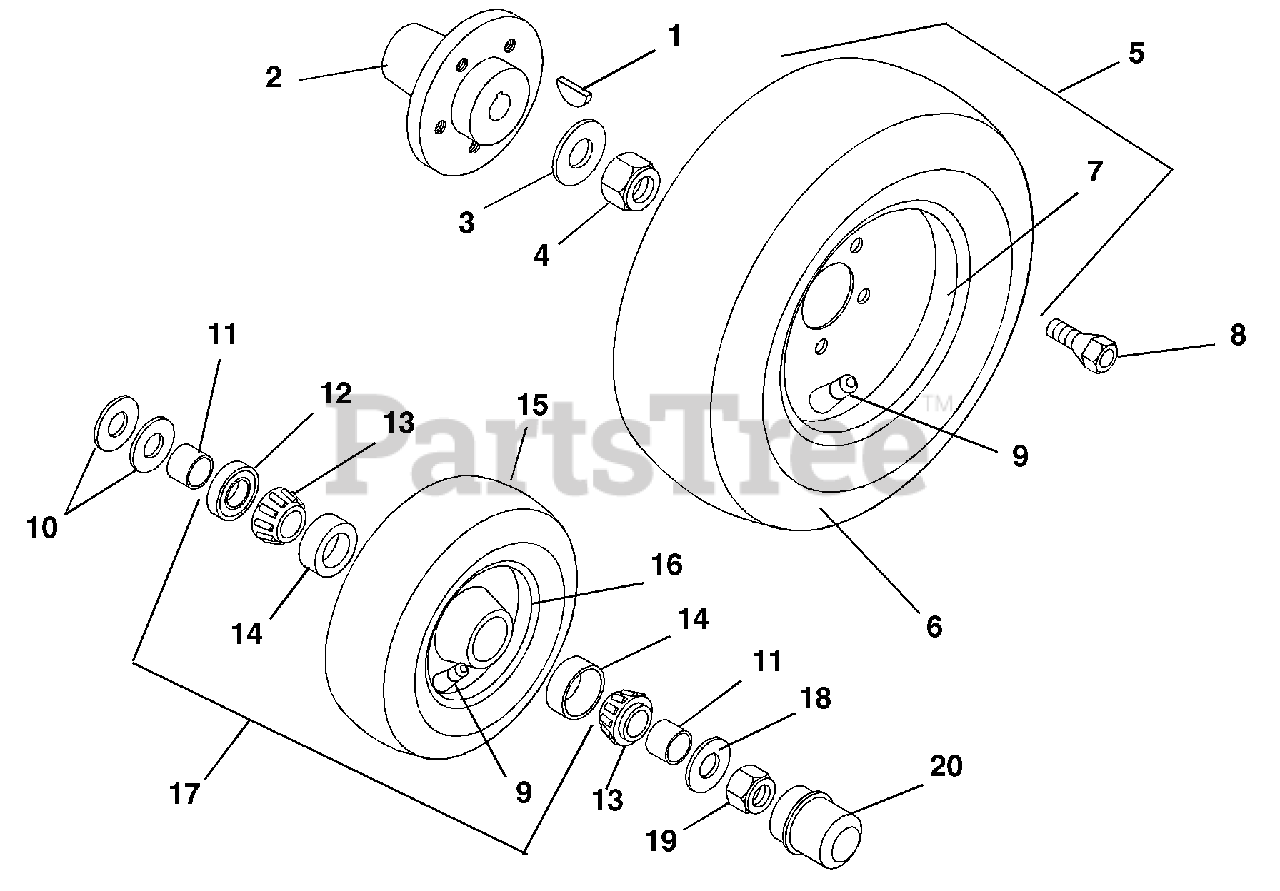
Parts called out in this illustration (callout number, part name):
1	Key-Woodruff .25 x 1.38 x .41 SAE 127
2	Hub, Tapered 4-Wheel
2	Hub
3	Washer-Flat-Steel.81 x 2.00 x .148
4	Nut-Locking-Center .75-10
5	Tire/Wheel Assembly 23 x 8.5-12
5	Tire/Wheel Assembly 23 x 10.50-12
6	Tire, Rear 23 x 8.50-12
6	Tire, 23 x 10.50-12
7	Weldment, Rim
8	Bolt, Lug .44-20 x 1.00
9	Valve Stem Assembly
10	Washer-Flat-Steel .81 x 1.50 x .135
11	Spacer .75 x 1.00 x .50
12	Seal 1.21 x 1.79 x .47
13	Bearing-Cone .75 x .61
14	Bearing-Cup 1.78 x .48
15	Tire,Front 16 x 6.50-8
15	Tire, 16 x 7.50-8
16	Weldment, Rim
17	Tire/Wheel Assembly 16 x 6.50-8
17	Tire/Wheel Assembly 16 x 7.50-8
18	Washer-Flat-Steel .67 x 1.31 x .095
19	Nut-Locking-Center .62-11
20	Dust Cap
